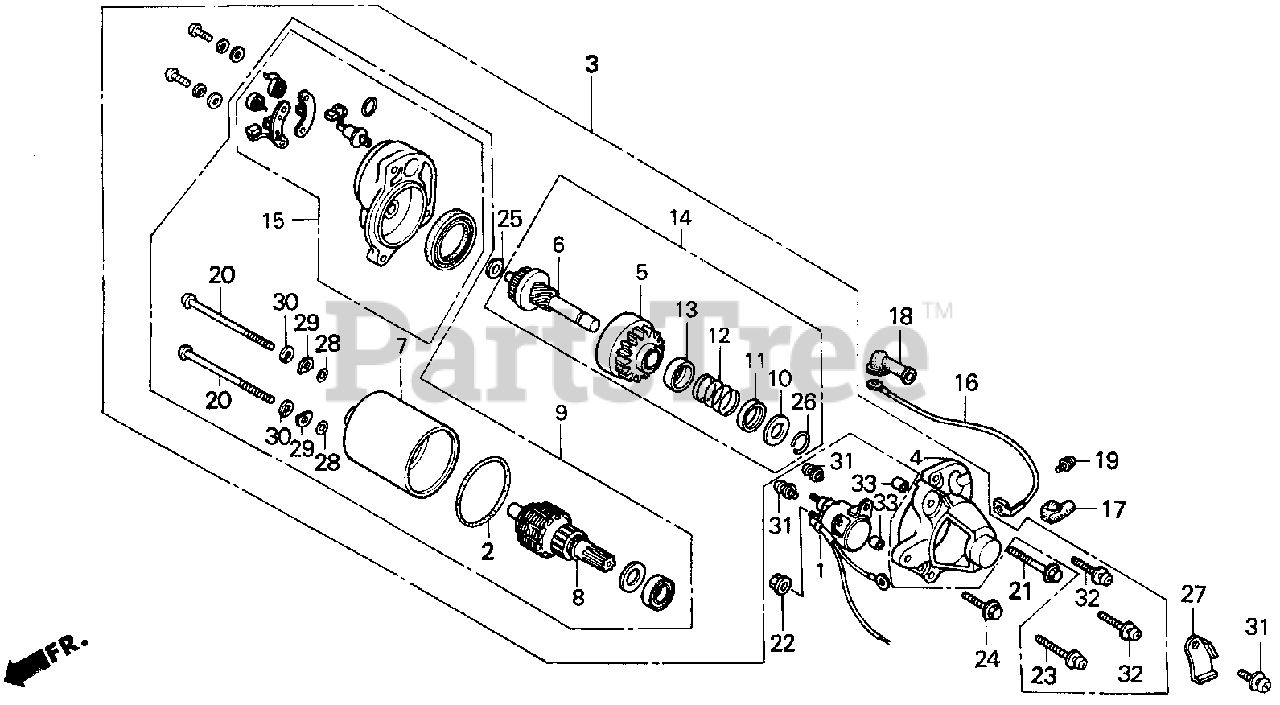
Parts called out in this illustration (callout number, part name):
1	SWITCH, MAGNETIC
2	O-RING
3	MOTOR UNIT, STARTER
4	COVER, GEAR
5	PINION ASSY.
6	SHAFT UNIT, GEAR
7	YOKE ASSY.
8	ROTOR ASSY.
9	MOTOR ONLY
10	PIECE A, STOPPER
11	PIECE B, STOPPER
12	SPRING, RETURN
13	COVER, SPRING
14	GEAR ASSY.
15	BRACKET, FR.
16	WIRE, MAGNET SWITCH
17	COVER, MAGNET SWITCH TERMINAL
18	COVER, STARTER MOTOR TERMINAL
19	SCREW-WASHER (5X8)
20	BOLT, SETTING
21	BOLT, FLANGE (6X32)
22	NUT-WASHER (6MM)
23	SCREW-WASHER (5X30)
24	BOLT, FLANGE (6X25)
25	WASHER, PINION
26	CIRCLIP (10.2MM)
27	HOLDER, HARNESS
28	O-RING
29	WASHER, SPECIAL
30	WASHER, SPRING
31	SCREW-WASHER (5X14)
32	SCREW-WASHER (5X20)
33	PIN A, DOWEL (8X10)
